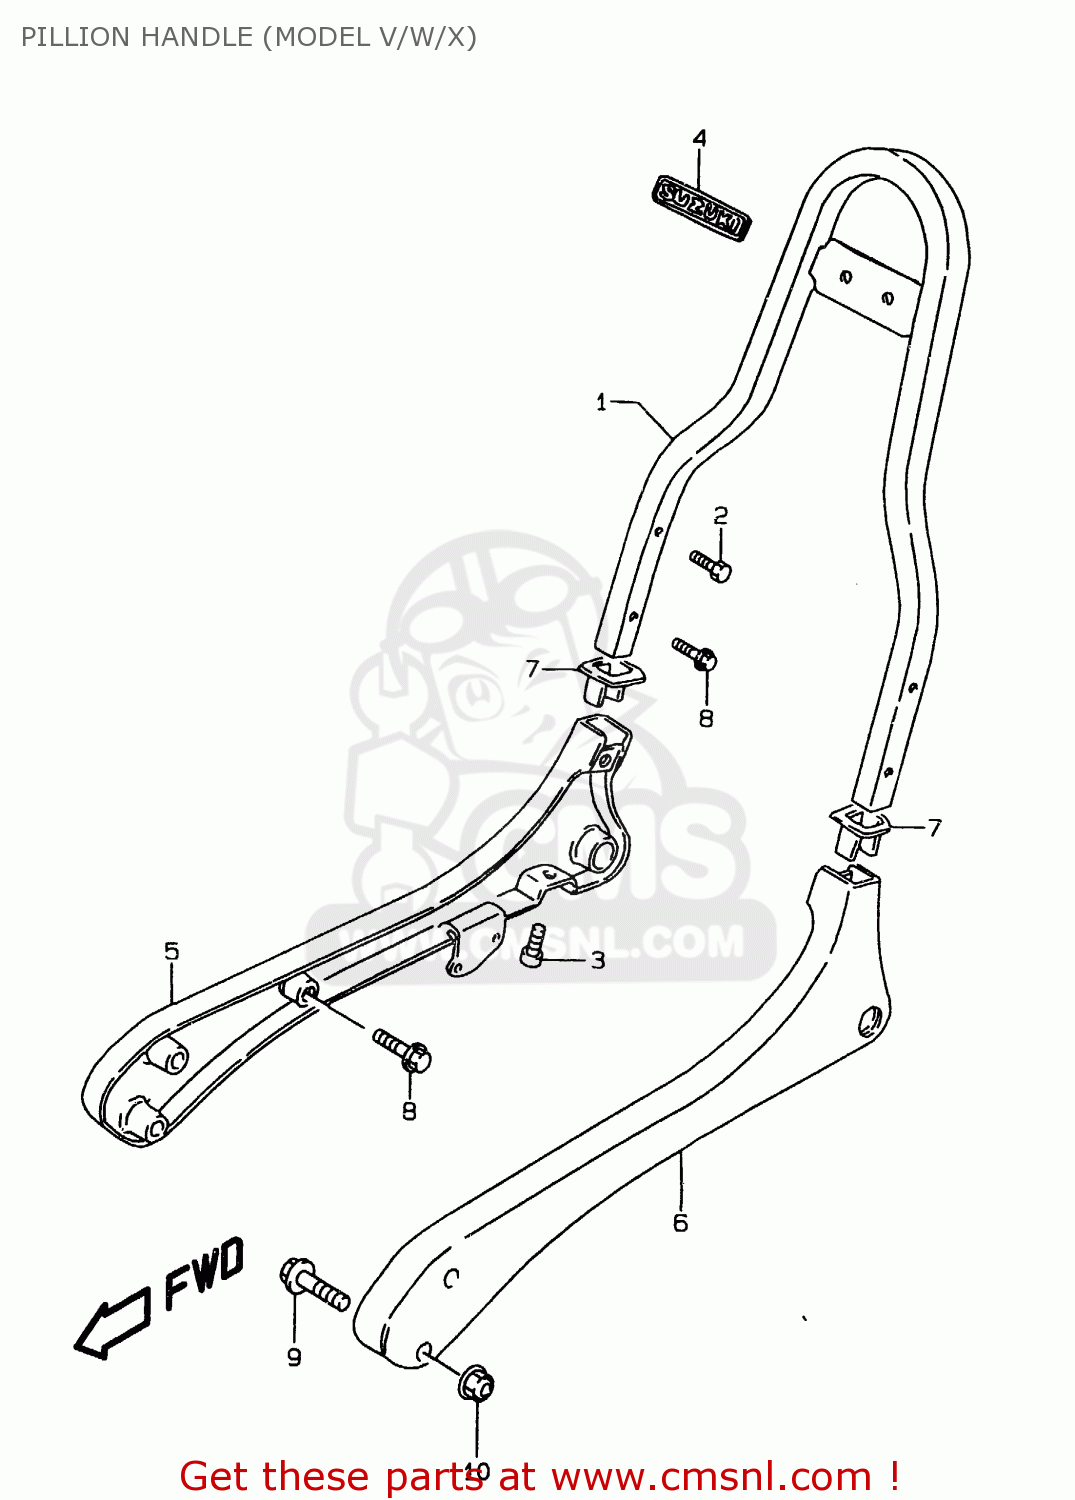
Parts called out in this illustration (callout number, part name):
1	HANDLE,PILLION UPR
2	BOLT
3	PLUG
4	EMBLEM
5	HANDLE,PILLION RIDER,R
6	HANDLE,PILLION RIDER,L
7	COVER,PILLION HNDL
8	BOLT
9	BOLT
10	NUT
